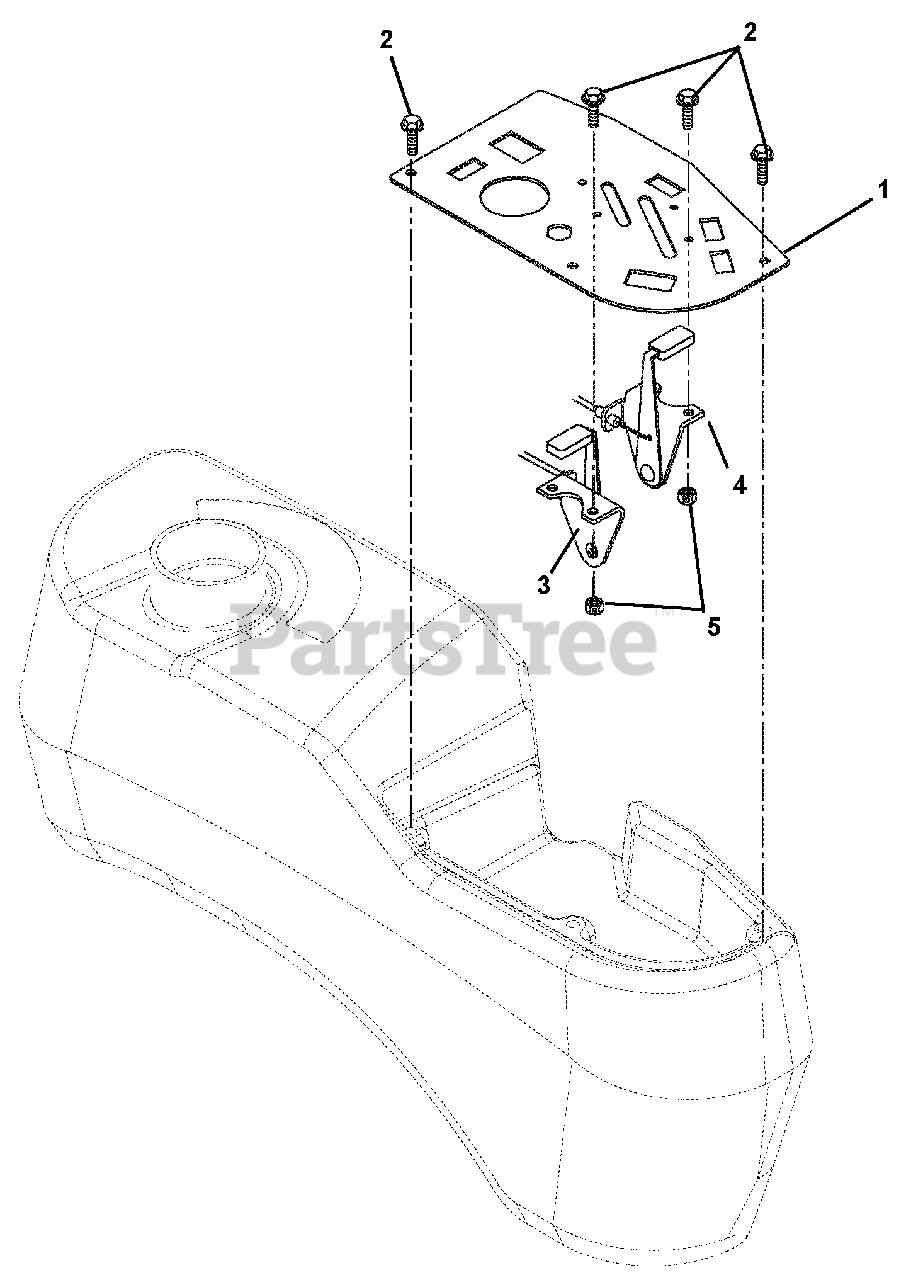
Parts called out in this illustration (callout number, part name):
1	Panel, Control
2	Screw, Machine 10-24 x .50 Hex Washer Head (045, 046, 047, 049, 052, 053, 066, 067, 068,
3	Throttle, Control
4	Choke Control (045, 046, 049, 066, 067, 070)
5	Nut, Locking Nylon 10-24 With Insert (045, 046, 047, 049, 052, 053, 066, 067, 068, 070, 071,
